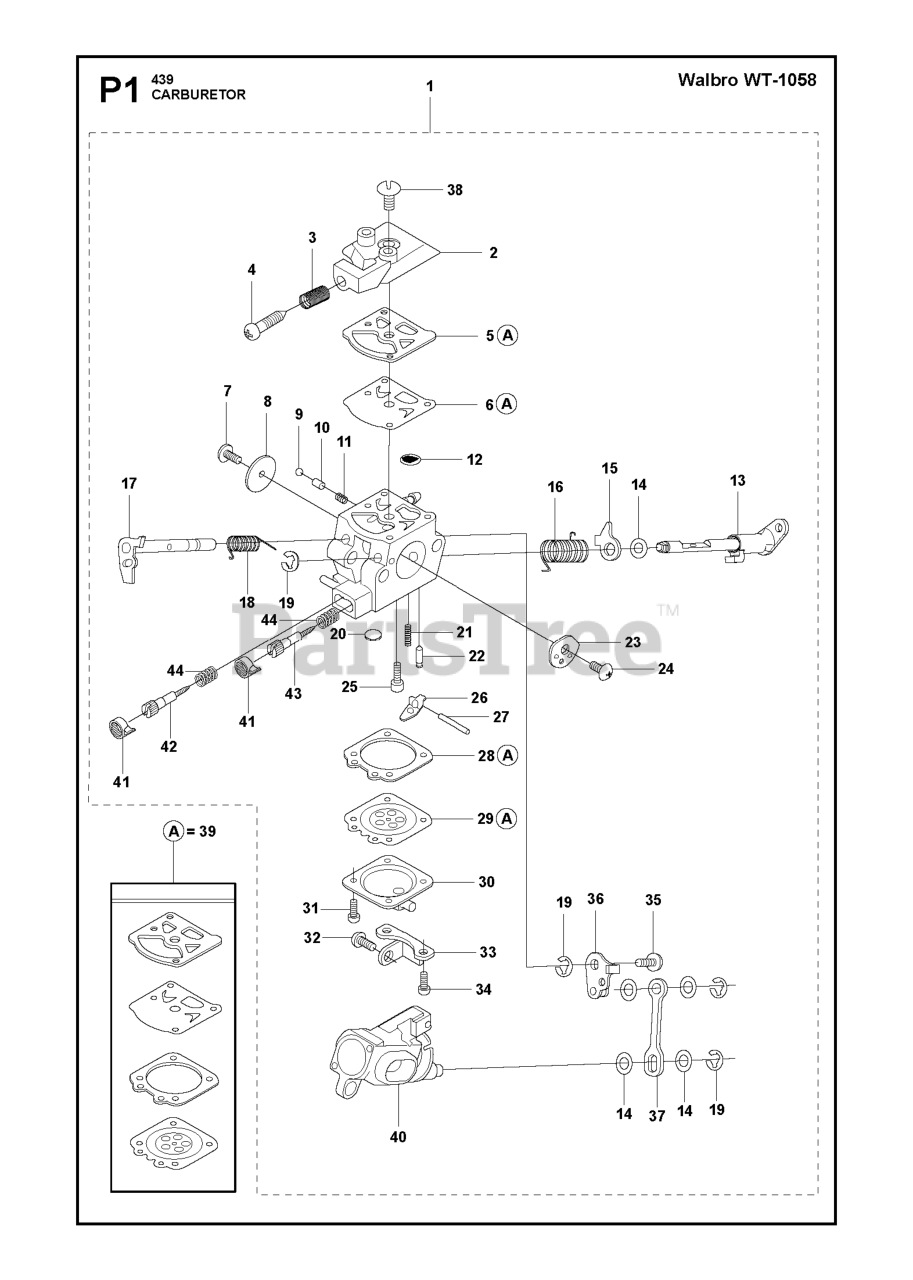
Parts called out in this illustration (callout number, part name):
1	CARBURETTOR 439
9	BALL
10	PISTON
12	SCREEN
13	SHAFT ASSY CHOKE 439
17	SHAFT ASST THRO
18	SPRING RETURN
22	VALVE INLET
23	CHOKE VALVE
31	SCREW ASSY
33	BRACKET 167-596
34	SCREW ASSY
36	LINK ASSY THROT 439
39	GASKET KIT
40	BODY ASSY AIR VALVE 5-8416
41	CAP LIMITER
